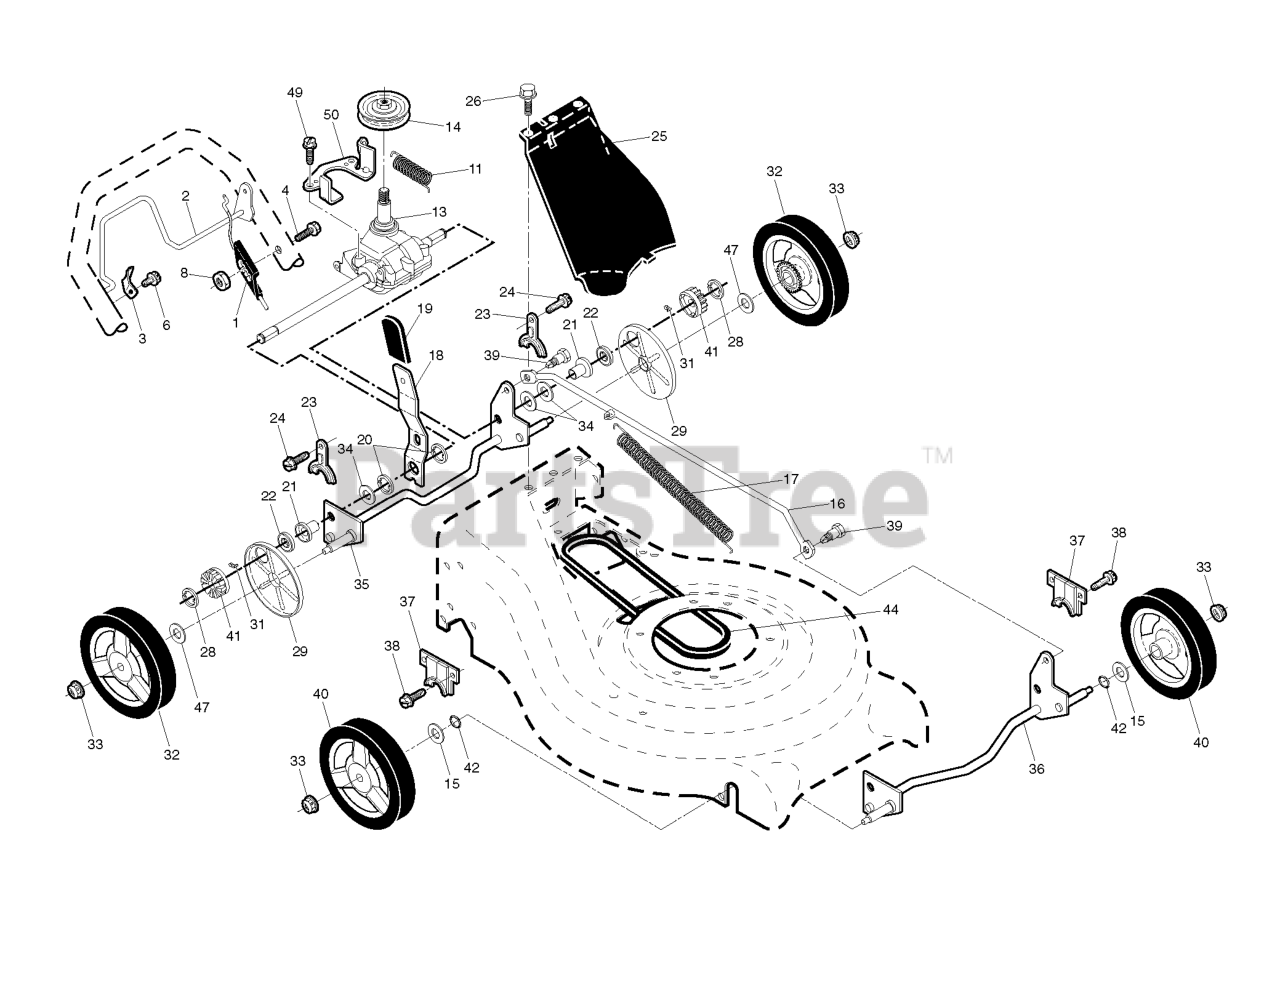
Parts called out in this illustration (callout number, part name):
3	DOWNSTOP BRACKET
8	NUT.HEX.FLANGE.1/4
13	TRANSMISSION.21.RWGD
14	PULLEY.RGD.SS.3.25OP
15	WASHER.FLAT.1/2
16	ROD.CONNECTING.SPT.BLACK
17	SPRING EXTENSION
18	SPRING.SELECTOR.
19	KNOB.EXT.ERGO.BLACK
21	BEARING SUPPORT
22	BEARING
23	BRACKET
24	SCREW 14-20 X 5/8
25	COVER.DRIVE.21.RWGD.MO
28	E-RING 7/16 RE
29	COVER.DUST.WHEEL
31	PAWL, DRIVE
32	WHEEL & TIRE ASSY, REAR
33	NUT.HEX.FLANGE.3/8-16.LO(3 2)
35	SHAFT ASSY REAR
36	SHAFT ASSY, FRONT
37	RETAINER.FRONT.SHAFT
39	SHOULDER BOLT SEMI GIMLET PT.
40	WHEEL & TIRES ASSY, FRONT
41	PINIION.14.TOOTH.RGD
42	O-RING..070X.487.NEOPRENE
44	RP.BELT.DRIVE.RGD.SS.WALK
47	WASHER FLUT
50	BRACKET.BELT.KEEPE/AUT*SUBS/2*
